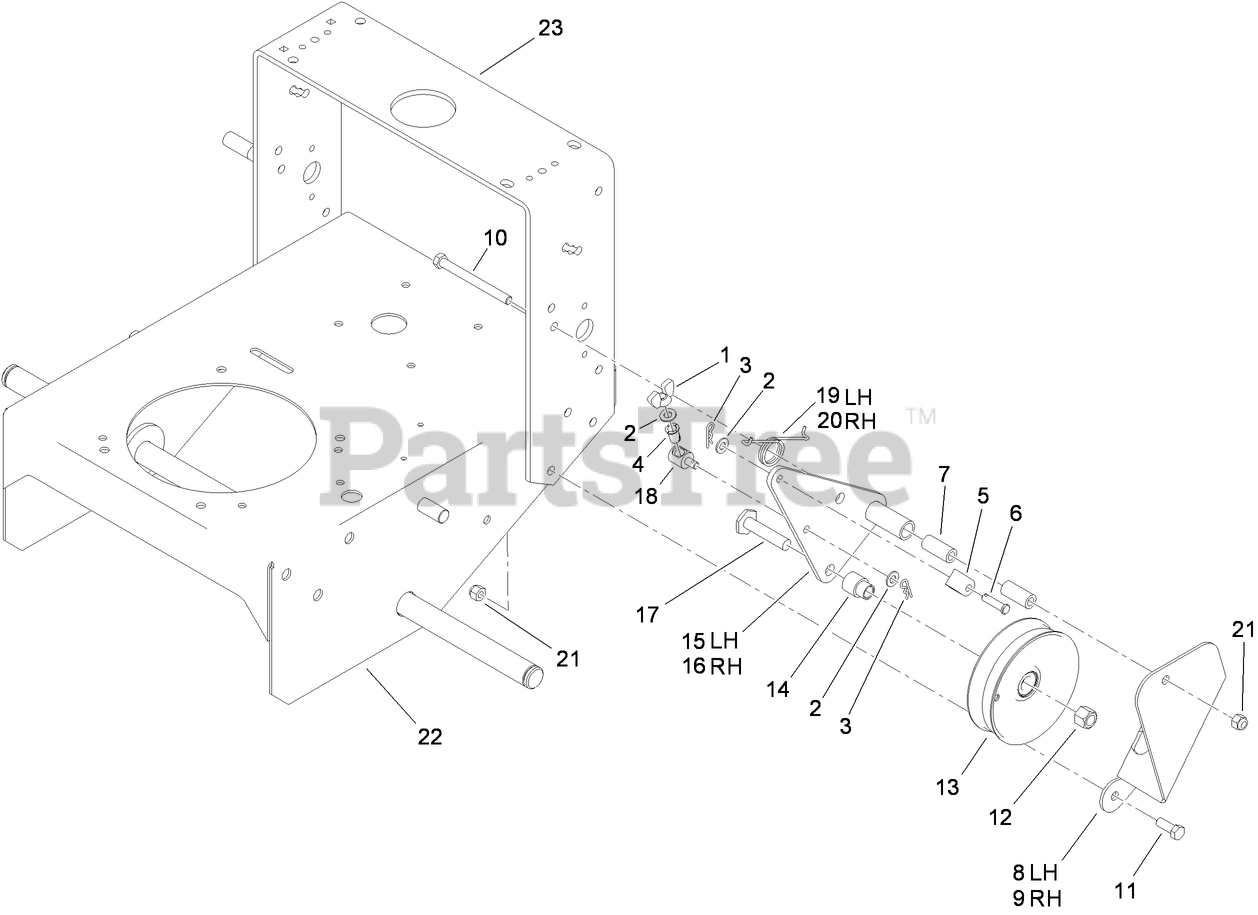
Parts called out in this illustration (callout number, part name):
1	NUT-WING
2	WASHER-PLAIN
3	PIN-COTTER
4	BUSHING-NYLON
5	FITTING-ROD
6	PIN-CLEVIS
7	SPACER-PIVOT, IDLER
8	BRACKET-SUPPORT, LH
9	BRACKET-SUPPORT, RH
10	SCREW-HH
11	SCREW-HH
12	NUT-LOCK, NI
13	PULLEY-IDLER
14	SPACER-PULLEY
15	ARM-IDLER, LH
16	ARM-IDLER, RH
17	SCREW-LEVELER
18	FITTING-ROD
19	SPRING-TORSION, LH
20	SPRING-TORSION, RH
21	NUT-LOCK, NI
22	GEAR FRAME ASM
23	FRAME-UPPER
